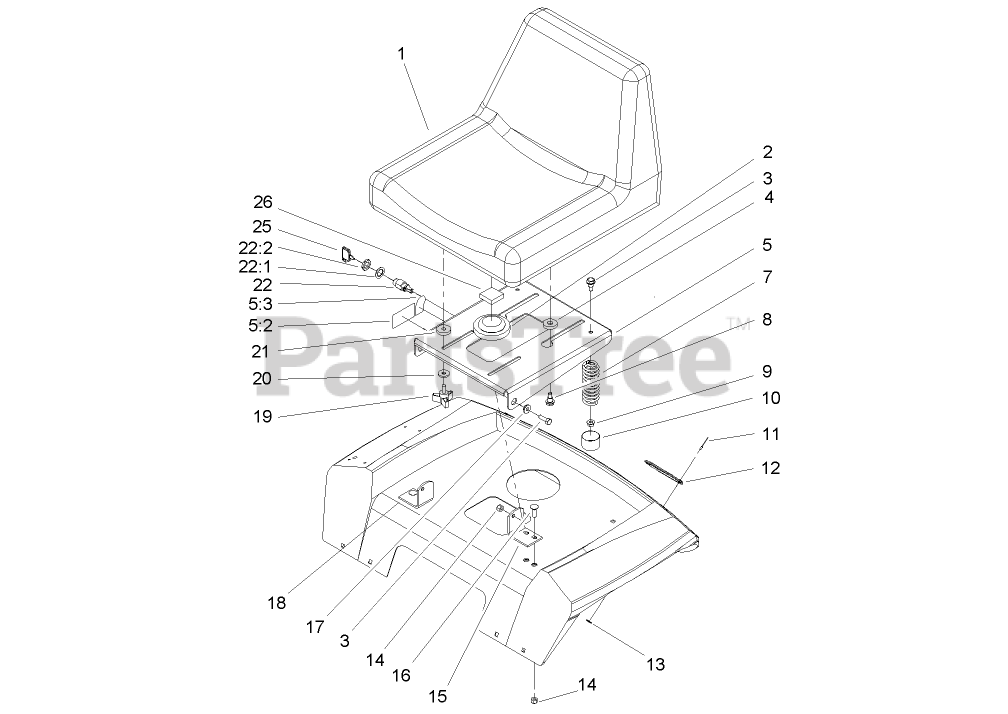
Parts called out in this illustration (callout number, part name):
2	SWITCH-SEAT
3	SCREW-HH
4	SPACER-NYLON
5	SUPPORT SEAT ASM
5:2	DECAL-DANGER
5:3	DECAL-SWITCH, NMIR
7	SPRING-COMPRESSION
8	BOLT-SHOULDER
9	NUT-HF
10	CAP-PROTECTOR
11	RIVET-BLIND
13	WASHER-PLAIN
14	NUT-LOCK, NI
15	BRACKET-PIVOT, RH
16	SCREW-CARR
17	BUSHING
18	BRACKET-PIVOT, LH
20	WASHER
21	SPACER-NYLON
22	STARTER SWITCH ASM
22:1	WASHER-LOCK
22:2	NUT-HH
25	KEY-IGNITION
26	FOAM-SWITCH, SEAT
